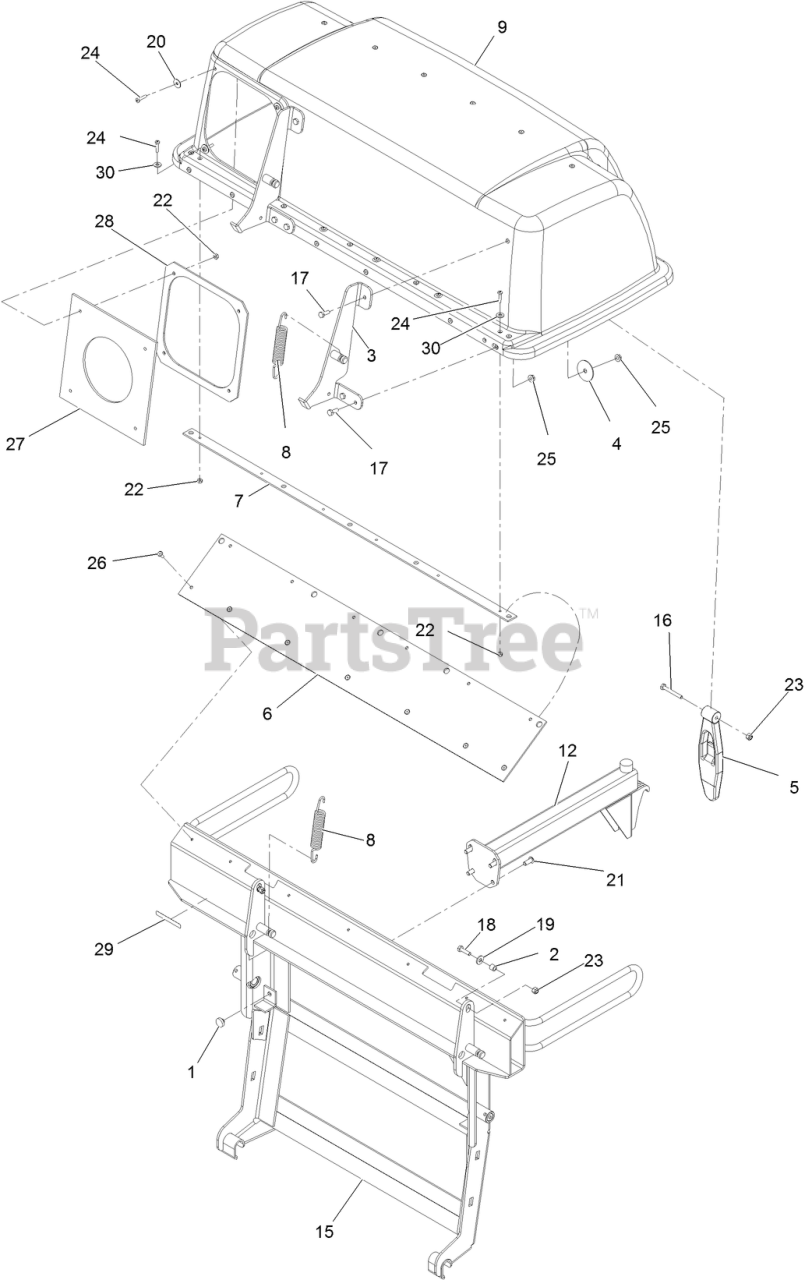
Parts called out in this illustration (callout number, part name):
3	HINGE ASM
7	PLATE-BACKING
8	SPRING-EXTENSION
9	ASM, HOOD
12	BAG SUPPORT ASM
15	FRAME-BAG, TWIN
16	SCREW-HH
17	SCREW-HH
18	SCREW-HH
19	WASHER-FLAT
20	WASHER-FLAT
21	SCREW-HSBH
22	NUT-LOCK, NI
23	NUT-LOCK, NI
24	SCREW-PPH
26	RIVET-BLIND
27	SEAL-CHUTE
28	CLAMP-SEAL
29	DECAL-WARNING
30	WASHER-FLAT
